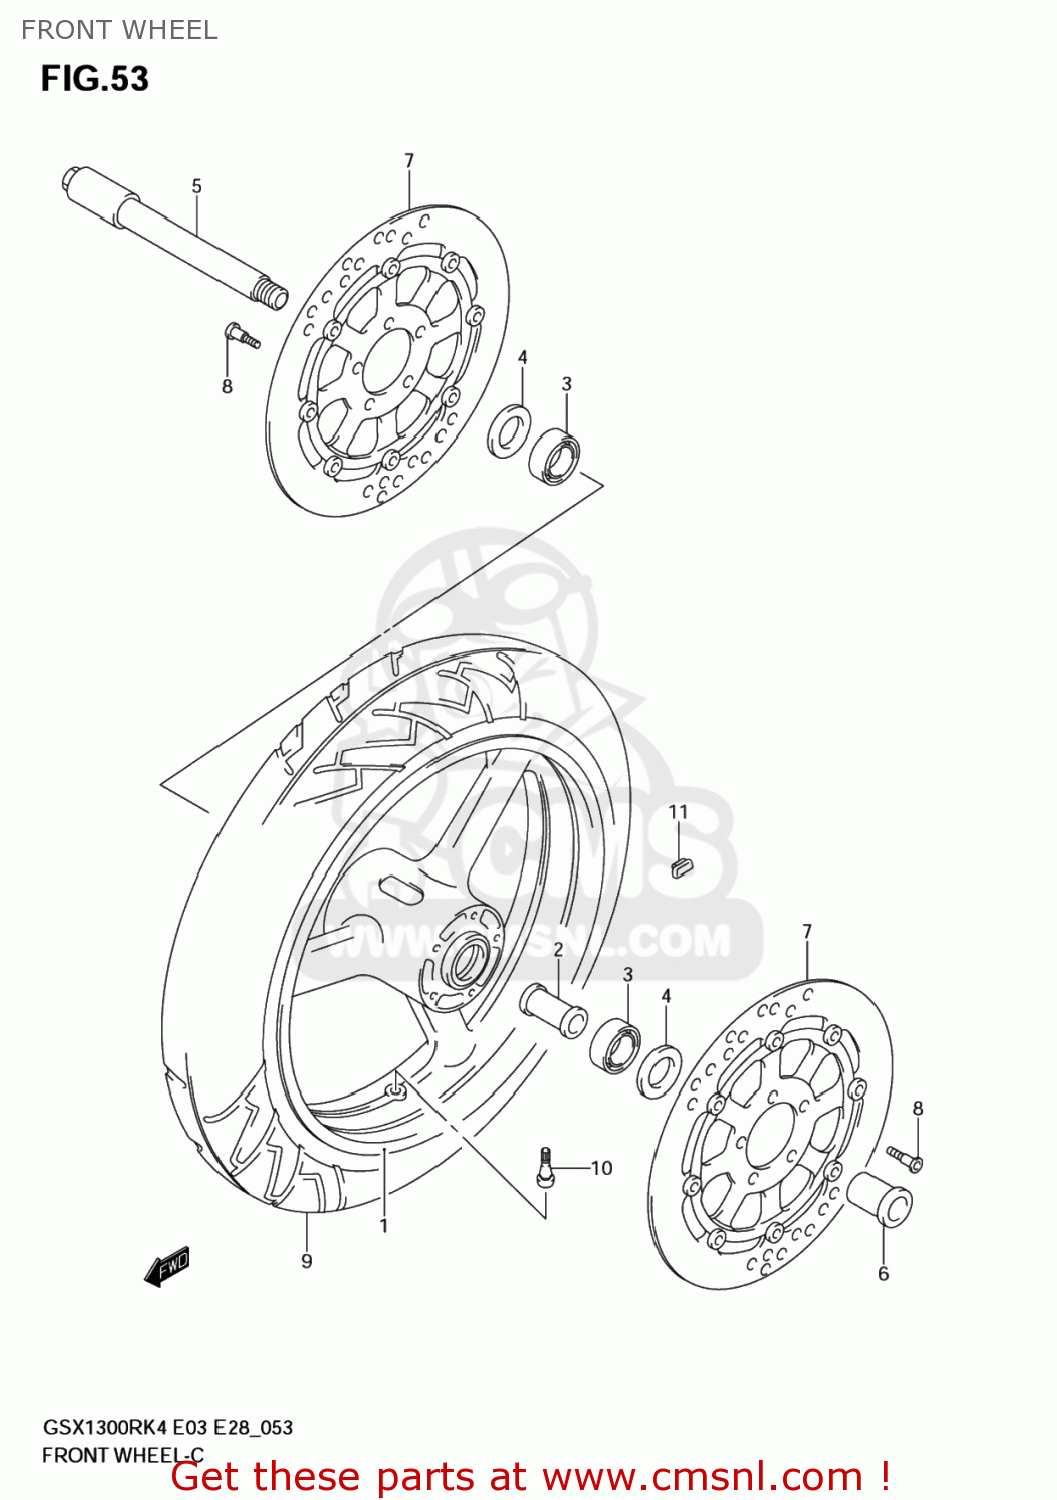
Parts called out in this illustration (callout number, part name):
1	WHEEL,FR(17M/CXMT3.50)
2	SPACER,FR HUB BEARING
3	BEARING(25X52X15)
4	SEAL,OIL(32X52X7)
5	AXLE,FR
6	NUT,FR AXLE
7	DISC,FRONT BRA
8	BOLT(8X33)
9	TIRE,FR(120/70 ZR17 58W)
10	VALVE ASSY,WHEEL RIM(TR412)
11	BALANCER,WHEEL(10G)
